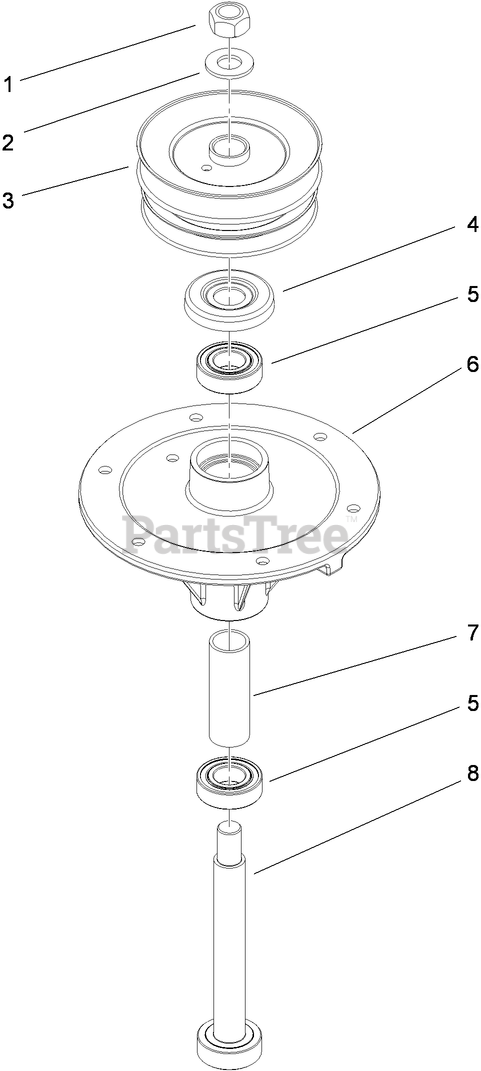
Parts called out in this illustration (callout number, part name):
1	NUT-HEX
2	WASHER
3	PULLEY AND HUB ASM
4	SHIELD-BEARING
5	BEARING-BALL
6	HOUSING-SPINDLE
7	SPACER-BEARING
8	SHAFT-SPINDLE
